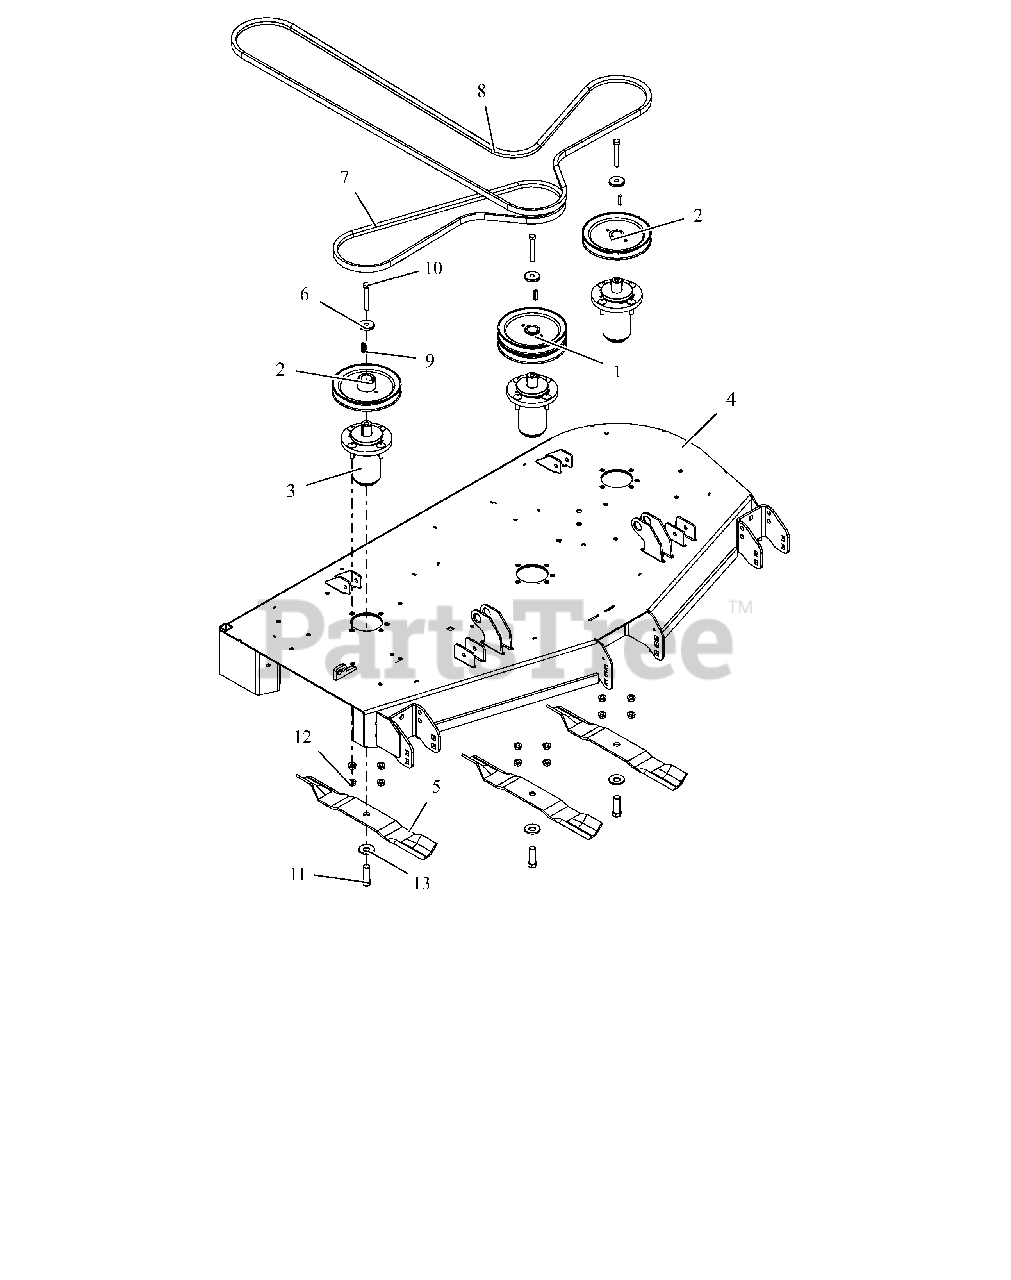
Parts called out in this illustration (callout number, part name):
1	PULLEY, DOUBLE-1"ID X 6.75"OD
2	PULLEY, V-1" ID X 6.75" OD
3	ASM, MAINT FREE ALUM SPINDLE
4	KIT,DECK-52" W/DECALS-GRAVELY
5	BLADE, 18"
6	RETAINER, SHEAVE
7	V-BELT, B-COGGED
8	V-BELT, HB SECTION
9	KEY, SQ .25X.25X1.00 RC 40-50
10	BLT, HEX .38-16X2.75 G8 ZCC
11	BLT, HEX .62-18X1.75 G8 ZCC
12	NUT-LK-CTR-FLG .375-16 GF ZCC
13	WSHR-BLVL .669X1.535X.138
